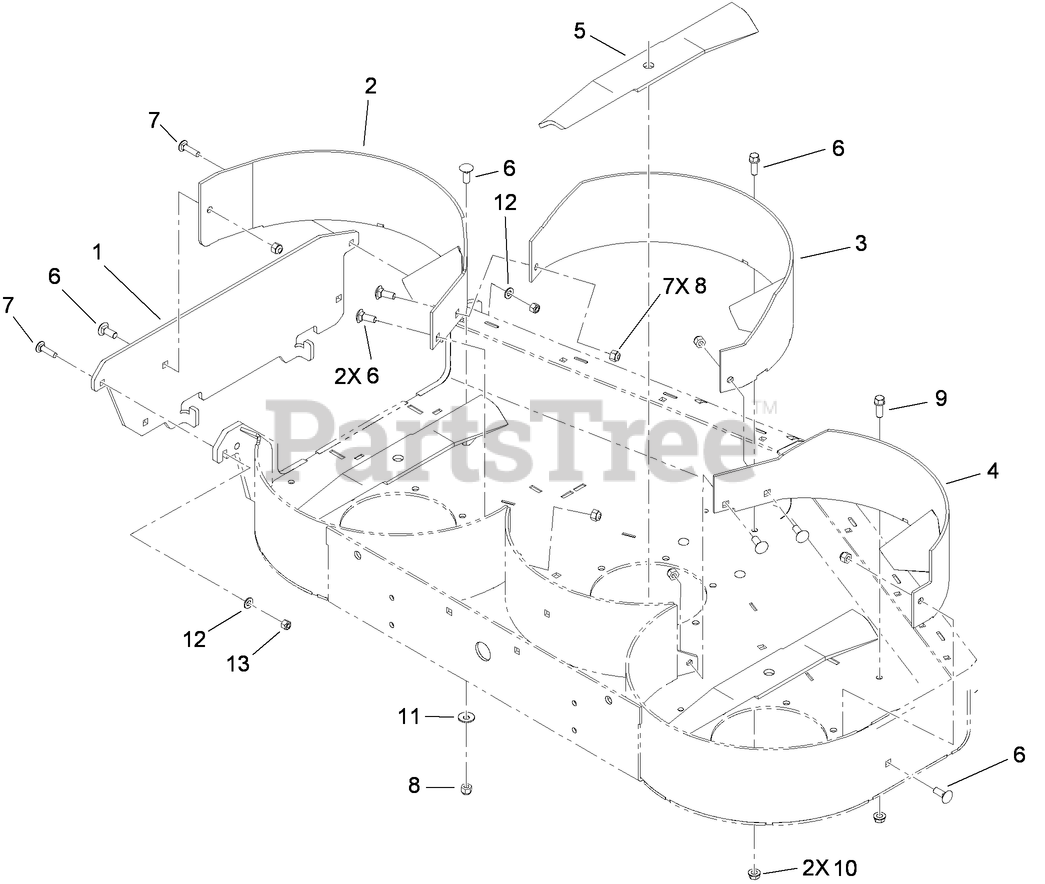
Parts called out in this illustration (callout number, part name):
1	PLATE-COVER, DISCHARGE
2	RH BAFFLE ASM
3	CENTER BAFFLE ASM
4	LH BAFFLE ASM
5	BLADE-RECYCLER, 16.5 INCH
6	BOLT-CARR
7	SCREW-CARR
8	NUT-LOCK, NI
9	SCREW-HWH
10	NUT-HHF, WHIZ
11	WASHER-BELLEVILLE
12	WASHER-PLAIN
13	NUT-LOCK, NI
